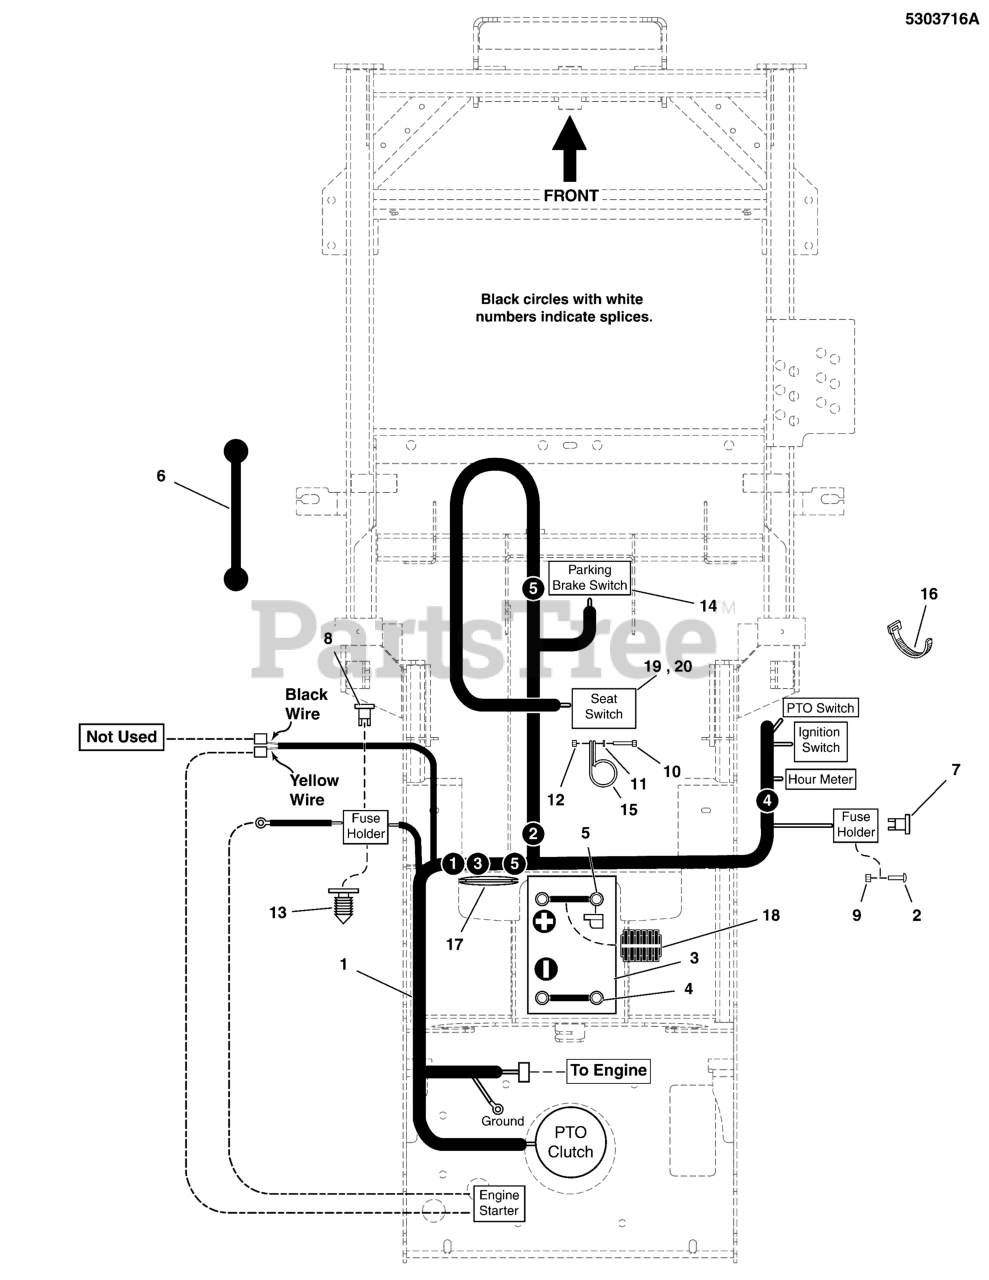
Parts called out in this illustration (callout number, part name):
1	WIRE HARNESS, MAIN, SM, ZTR
1	HARNESS, Wiring, Small ZTR
3	BATTERY, 11U1L, 350 CCA
4	BATTERY CABLE, NEG, 14, 5/16-13/32
5	BATTERY CABLE, POS, 22, 1/4-5/16
6	STRAP, BATTERY, 14 LONG, Rubber
7	FUSE, ATO-15 (15 AMP)(SV)
8	FUSE, ATO-20 (20 AMP)(SV)
9	NUT, Hex, 5/16-24
10	BOLT, 1/4"-20 X 3/4" GD5 YZ
11	WASHER, 1/4 SAE
12	NUT, 1/4-20 Hex Nylock Flange
13	FIR TREE MOUNT, PACKARD
14	SWITCH, DP NO/NC SNAP-IN
15	CLAMP, VINYL INSULATED, 1.00
16	TIE, SELF-LOCKING, 12"
17	GROMMET, 1-1/2" ID FOR 1/4" METAL
18	WIRE LOOM, 3/8 ID X 18 IN
19	SWITCH, NC, W/ BOLT-IN BASE
20	SWITCH, NC, W/ TWIST-IN BASE
